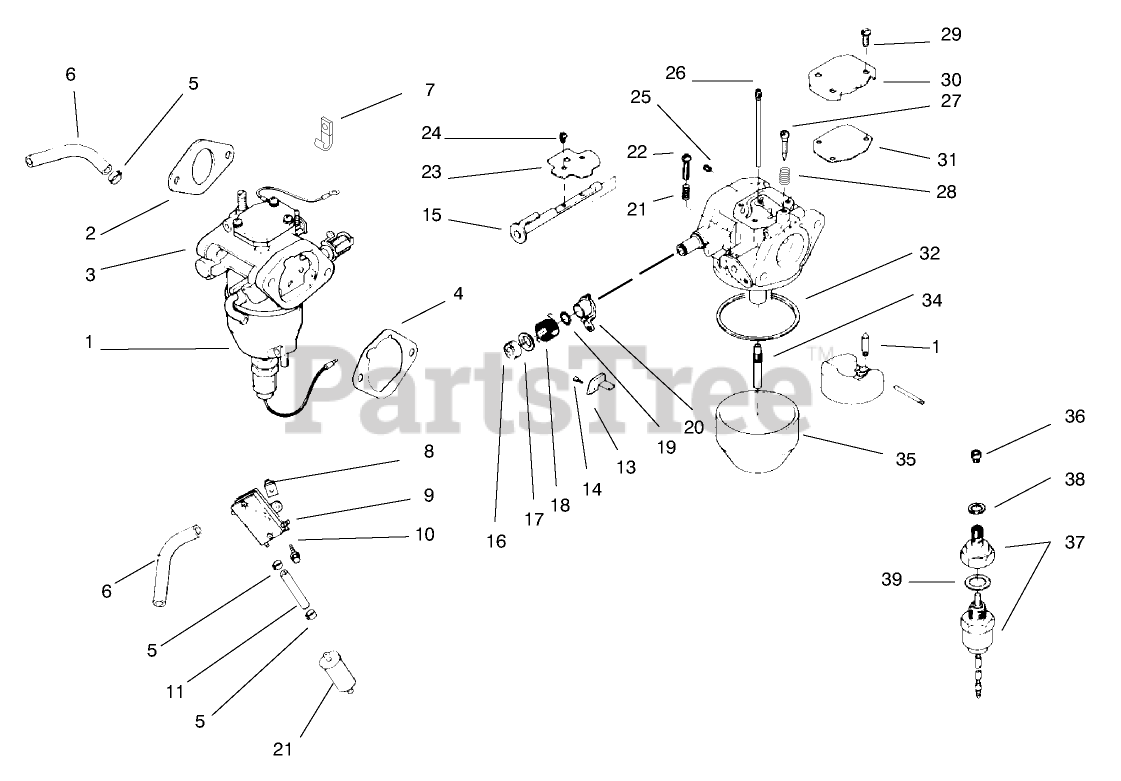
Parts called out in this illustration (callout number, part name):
1	Kit-Carburetor Incl.2-4
2	Kit-Carburetor
3	Carburetor (Ref)
4	Gasket-A/C Base
5	Clamp
6	Line-Fuel 12"
7	Clamp
8	Nut
9	Pump-Fuel
10	Screw
11	Line-Fuel
12	Filter-Fuel
13	Bracket-Throttle Stop
14	Screw
15	Shaft-Choke
16	Washer
17	Collar-Coke
18	Spring-Choke Return
19	Ring-Choke Lever
20	Lever-Choke
21	Sprin-Throttle Screw
22	Screw-Throttle Adjust
23	Valve-Choke
24	Screw
25	Jet-Air Bleed
26	Jet-Slow
27	Screw
28	Spring-idler Screw
29	Screw
30	Cover-Passage
31	Gasket-PassageCover
32	Gasket-FloatChamber
33	Kit-Float Repair
34	Nozzle-Main
35	Chamber-Float
36	Jet-Main
37	Kit-Solenoid INC41-42
38	Gasket-ChamberScrew
39	Gasket-Solenoid
